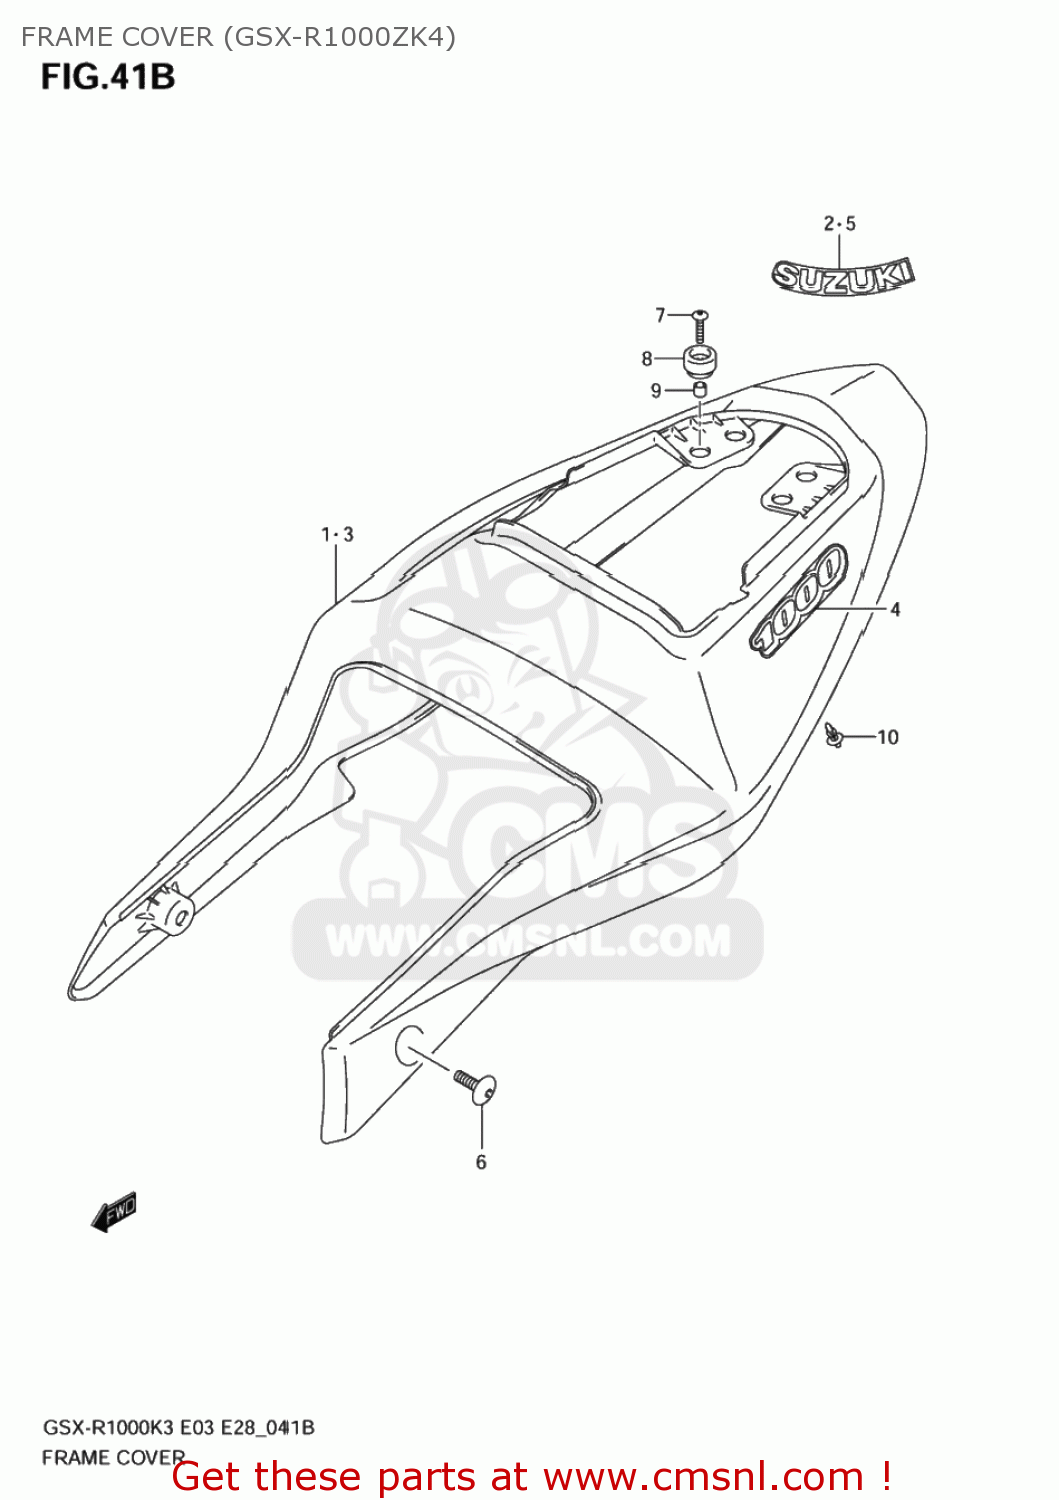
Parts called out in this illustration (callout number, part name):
1	COVER ASSY,FRAME(WHITE)
2	EMBLEM,SUZUKI
3	COVER ASSY,FRAME(BLACK)
4	EMBLEM,1000
5	EMBLEM,SUZUKI
6	SCREW(6X16)
7	SCREW(6X25)
8	SPACER(6.5X10X9.4)
9	CUSHION
10	CLIP(BLACK)
